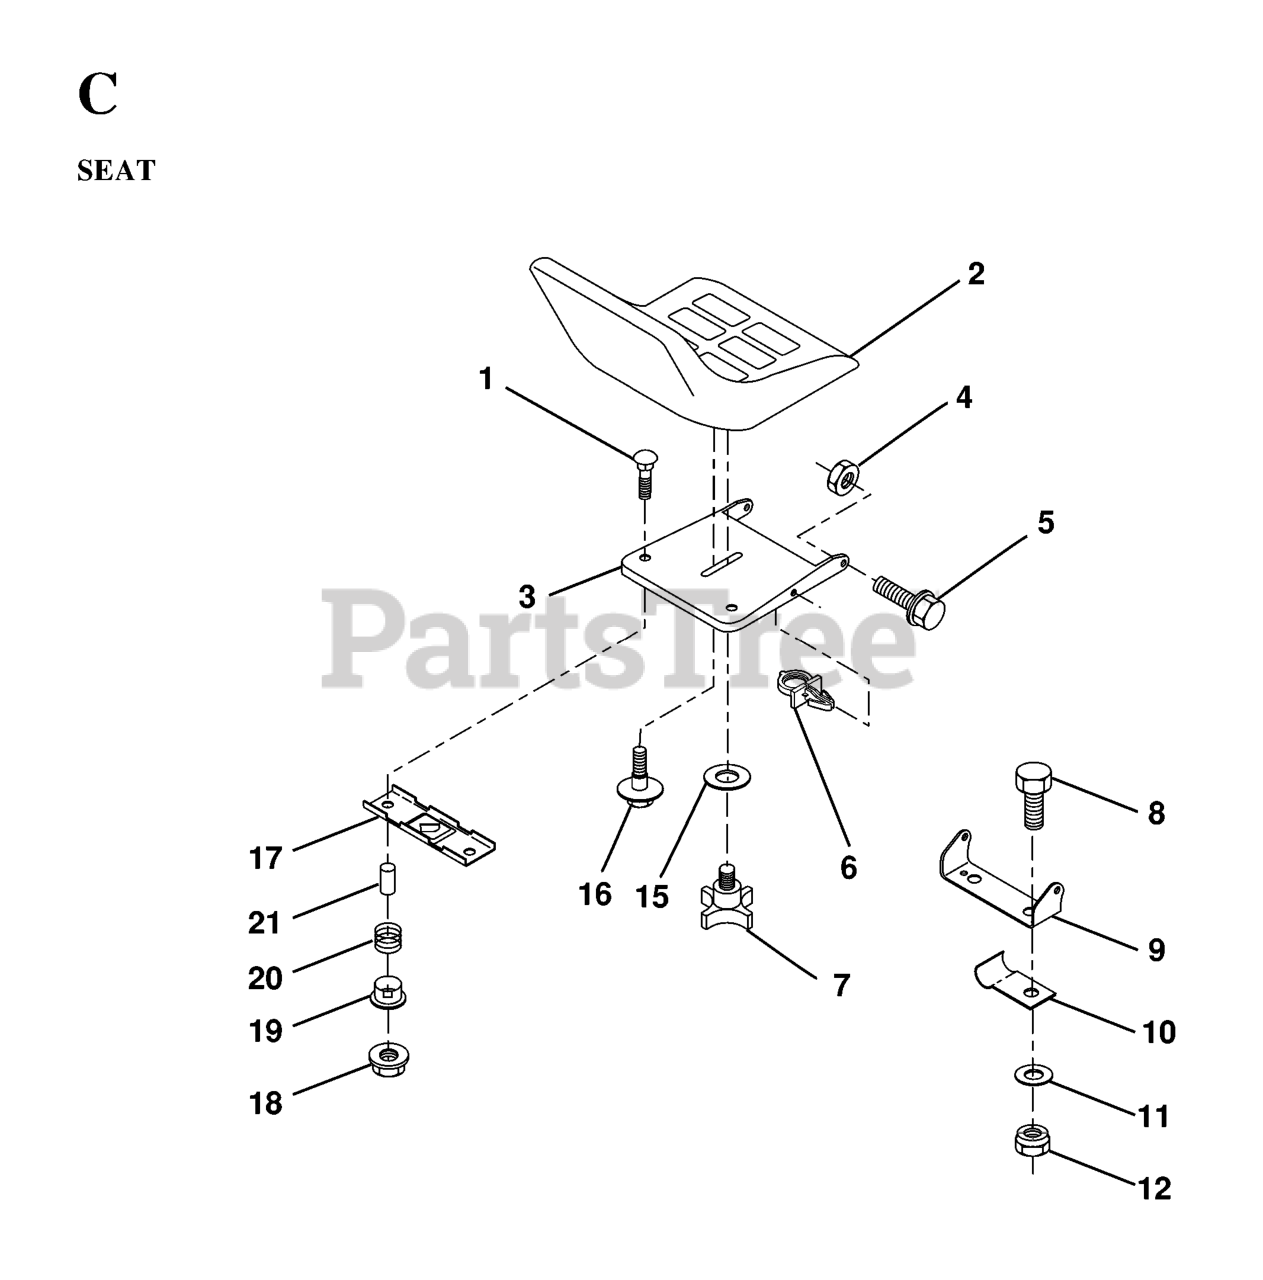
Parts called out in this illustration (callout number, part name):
1	Bolt Rdhd. Sht. Nk 1/4-20 x 1-3/8
2	SEAT
3	PAN, SEAT
4	NUT.71038.31-18.HEX.NYLOCK
5	BOLT SHOULDER 5/16-18
7	KNOB 1/2" YT
8	BOLT
9	SEAT PIVOT BRKT
10	CLIP,INSULATOR
11	WASHER 12/32X2X10GA
12	NUT
16	BOLT,SHOULD
17	BRKT SWITCH
18	NUT T
21	SPACER SPLIT 28X.96
